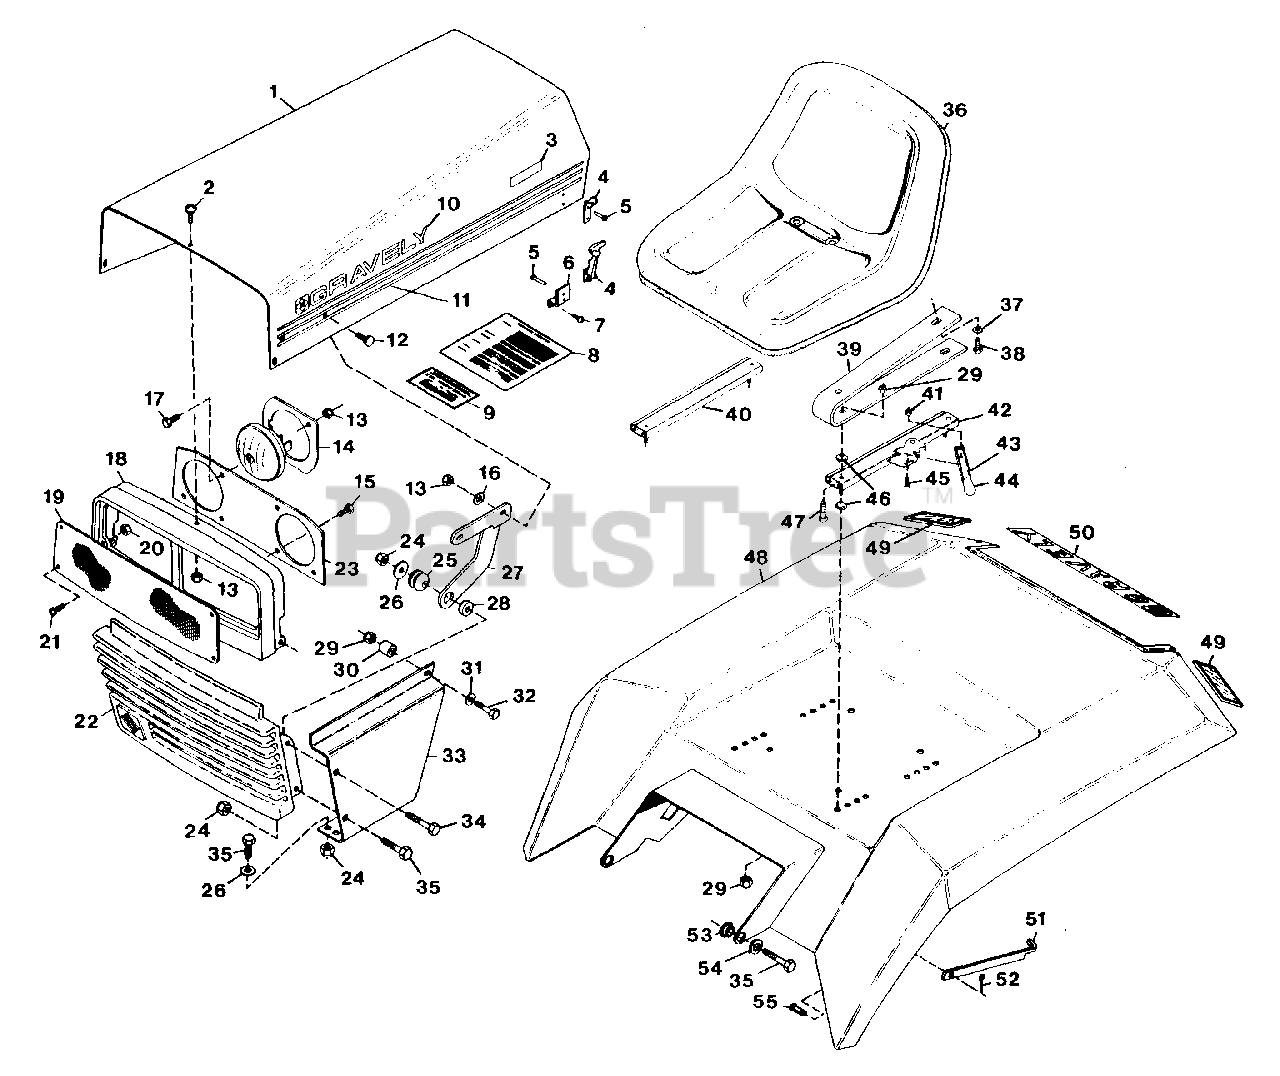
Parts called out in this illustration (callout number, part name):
1	HOOD, SILK SCREEN
2	SCREW, MACHINE 1/4-20 PHD
3	DECAL, MODEL 12-G
3	DECAL, MODEL 16-G
3	DECAL, MODEL 18-G
3	DECAL, MODEL 20-G
4	LATCH, FLEXIBLE
5	RIVET, DOME HEAD
6	BRACKET, HOOD LATCH MOUNTING
7	SCREW, 8-18X.375 PHD CR
8	DECAL, MAINTENANCE
9	DECAL, ELECTRICAL SYSTEM WARNING
10	DECAL, GRAVELY LOGO
11	DECAL, SIDE STRIPE L.H. AND R.H.
12	BOLT, 1/4-20X.75 RD HD SQ NK
13	NUT, LOCK 1/4-20
14	RING, HEADLIGHT RETAINER
15	SCREW, 1/4-20X.50 SELF-TAPPING
16	WASHER, FLAT .281X.625X.065
17	BOLT, HEX 1/4-20X1.00
18	BEZEL, HEADLIGHT
19	PANEL, HEADLIGHT LENSE
20	NUT, LOCK 10-24
21	SCREW, MACHINE 10-24X.75 PHD
22	CASTING, GRILLE
23	PANEL, HEADLIGHT REFLECTOR
24	NUT, LOCK 3/8-16
25	GROMMET
26	WASHER, FLAT .438X1.000X.083
27	HINGE, HOOD L.H.
27	HINGE, HOOD R.H.
28	SPACER
29	NUT, LOCK 5/16-18
30	SPACER, .375X.100X1.00
31	WASHER, FLAT .344X.688X.065
32	BOLT, HEX 5/16-18X1.75
33	PANEL, SIDE L.H.
33	PANEL, SIDE R.H.
34	BOLT, HEX 3/8-16X2.00
35	BOLT, HEX 3/8-16X1.00
36	SEAT, HIGH BACK
37	WASHER, LOCK 5/16 REG.
38	BOLT, HEX 5/16-18X.75
39	SPRING, SEAT
40	ADJUSTER, SEAT
41	NUT, LOCK 10-24
42	ADJUSTER, SEAT W/LATCH
43	HANDLE, SEAT SLIDE
44	TIP, LEVER
45	SCREW, MACHINE 10-24X.625 PHD
46	SPACER
47	BOLT, HEX 5/16-18X1.25
48	WELDMENT, SEAT PAN
48	WELDMENT, SEAT PAN NOTCHED
49	REFLECTOR, RED SAFETY
50	DECAL, GRAVELY LOGO
51	STRAP, FENDER HOLD-UP
52	PIN, COTTER .06X.75
53	BUSHING, REAR FENDER
54	WASHER, FLAT .406X.812X.065
55	PIN, CLEVIS .250X.406
